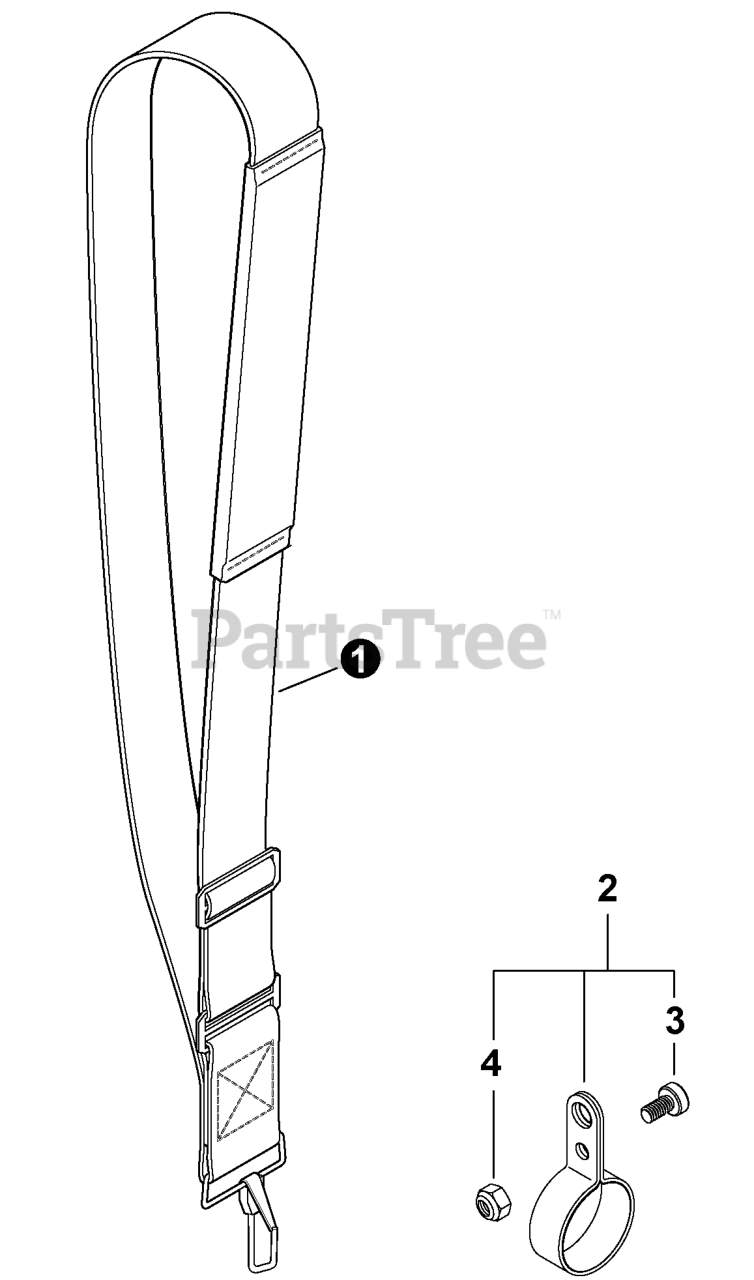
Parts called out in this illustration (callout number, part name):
1	STRAP ASSY, SHOULDER
2	HANGER KIT
3	BOLT, TORX 5x10
4	NUT, M5x8 NYLON INSERT
